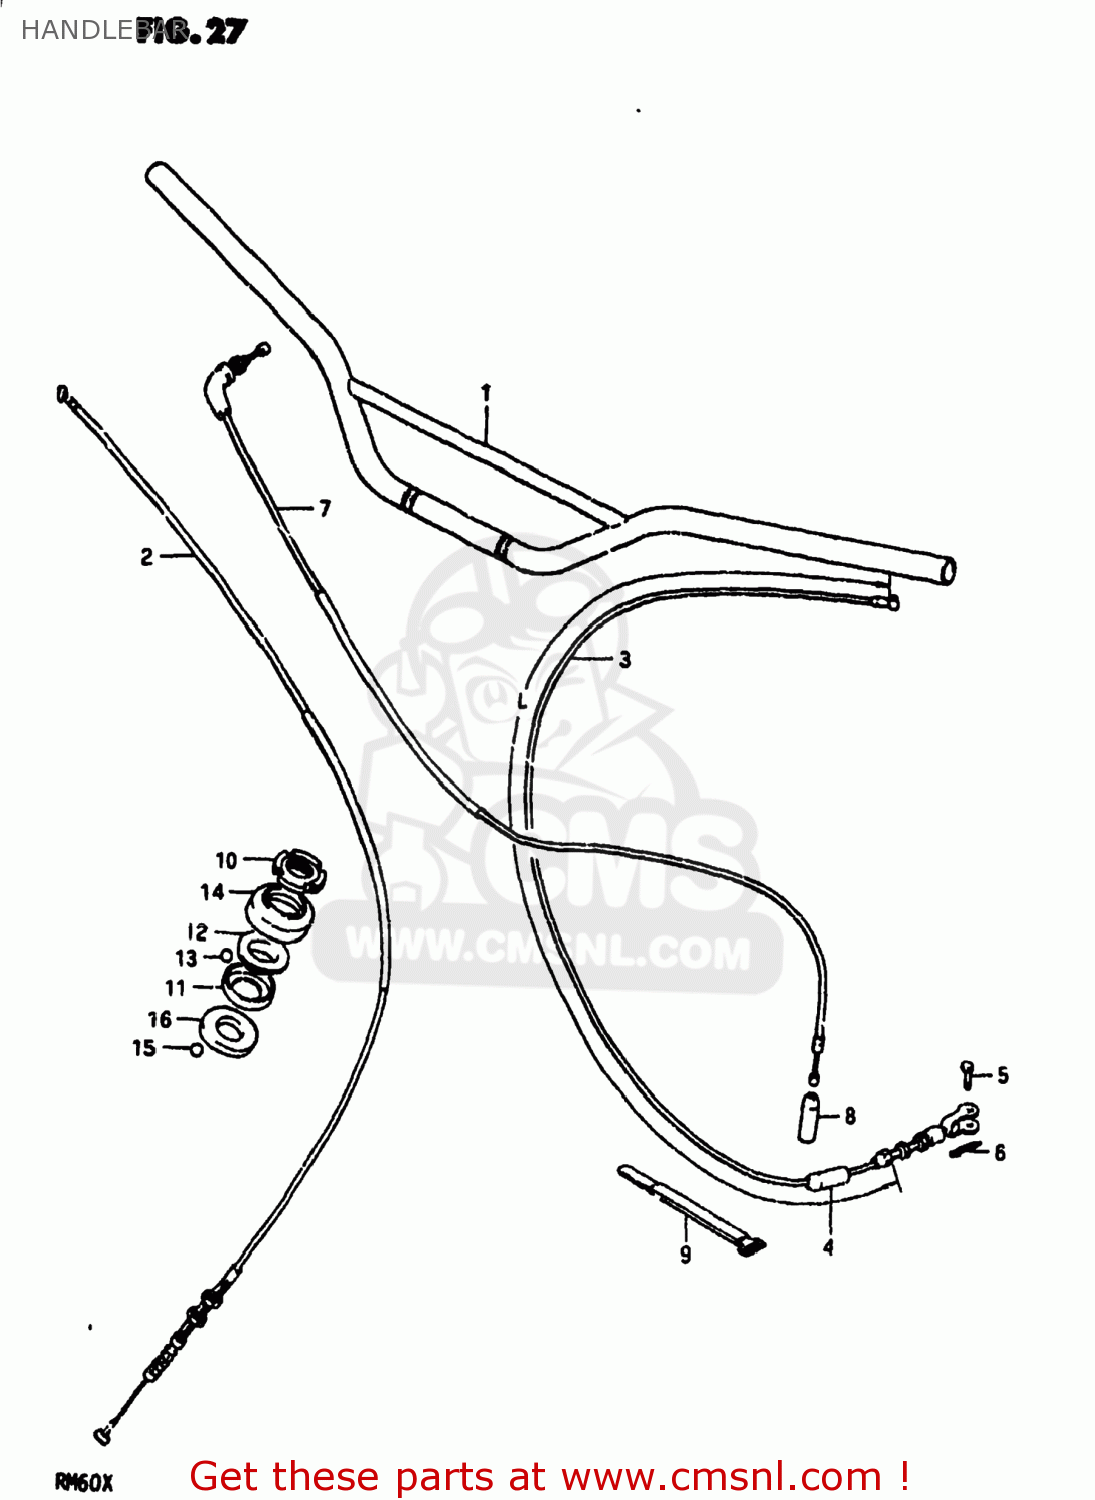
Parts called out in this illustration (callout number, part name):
1	HANDLEBAR
2	CABLE,FRONT BRAKE
3	CABLE ASSY,CLUTCH
4	SEAL,DUST(7X18X30)
5	PIN(L:13)
6	PIN
7	CABLE ASSEMBLY,THROTTLE
8	SEAL,DUST(7X18X30)
9	CLAMP
10	NUT,STEERING STEM(25X44X10)
11	RACE,STEERING INNER UPR
12	RACE,STEERING OUTER UPR
13	BALL
14	DUST SEAL,STEERING UPR
15	BALL
16	LACE,STEERING INNER LWR
